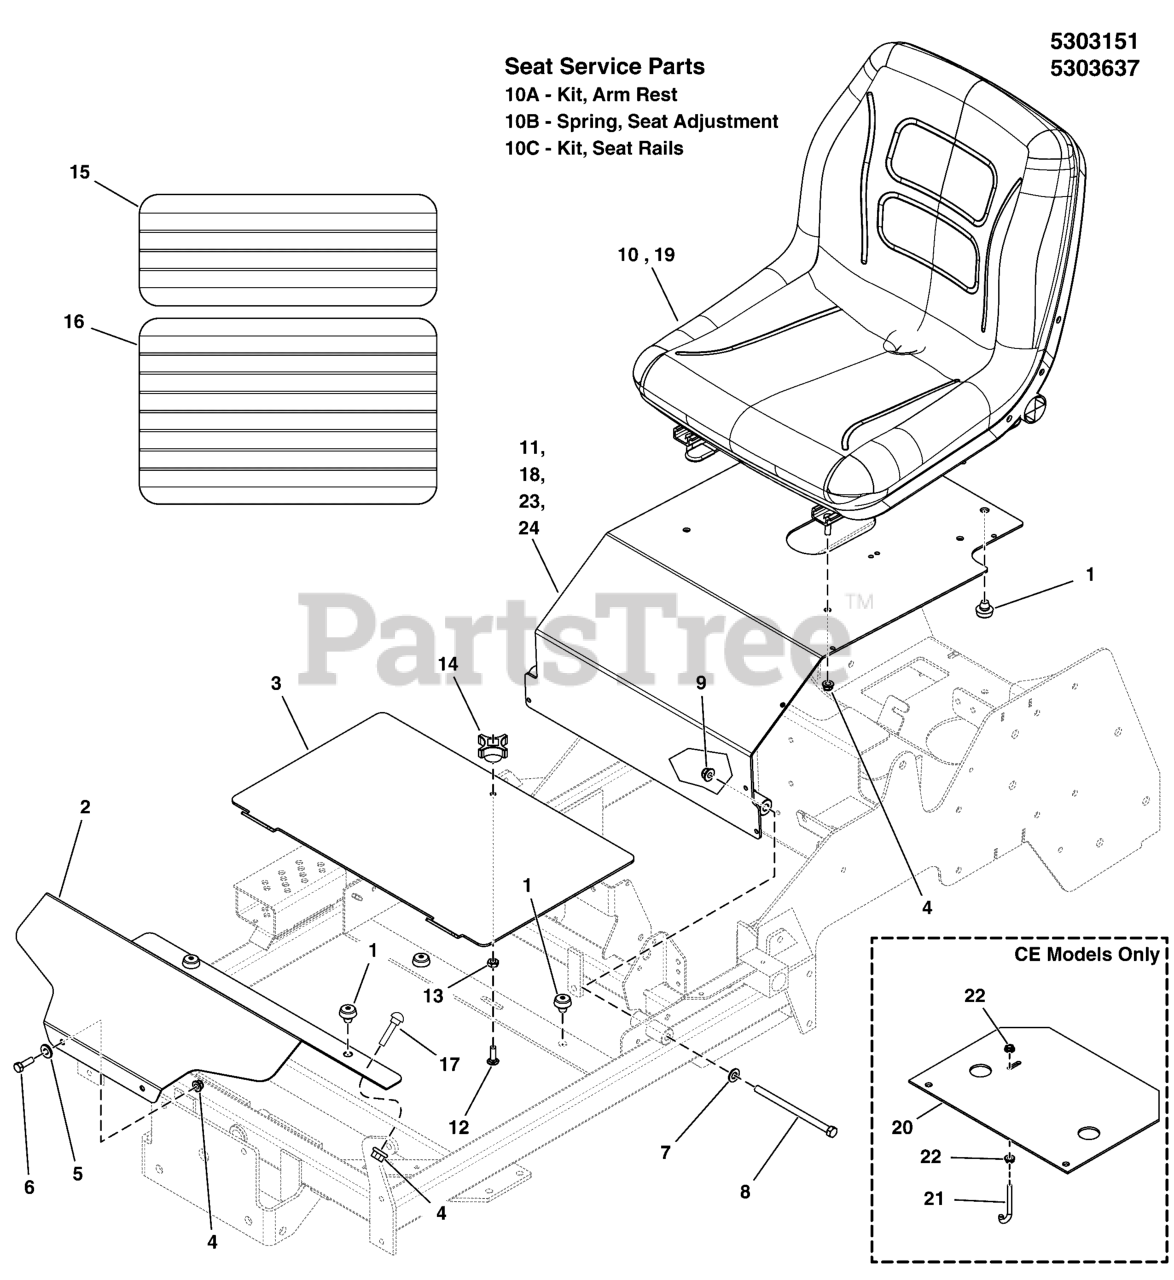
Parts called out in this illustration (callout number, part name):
1	MNT, VBRTN, RBBR
2	PLATE, Floor
3	PLATE, FLOOR PAN, REMOVABLE. IS600 - RED
4	NUT, 5/16-18 HEX NYLOCK FLANGE
5	WASHER, 5/16 F436 FLAT
6	BOLT, 5/16-18 X 1 GD5 YZ
7	WASHER, 3/8 SAE
8	BOLT, 3/8-16 X 6" GD5 CZ
9	NUT, 3/8-16 HEX NYLOCK FLANGE
10	SEAT, NO ARM REST
10A	ARMREST KIT
10B	SPRING, EXTENSION, SEAT ADJUSTMENT (BLK OR SLVR)
10C	SEAT RAIL, KIT, RH AND LH
11	ASSM, SEAT PLATE W/DECALS - IS600Z (5409894B)
12	BOLT, 5/16-18 X 1-1/4, CARRIAGE YZ
13	NUT, 5/16-18,GR8, HEX, CNTR, LK, ZINC/CL
14	KNOB-INT THR .312-18 4-ARM 2.12WD 1.06LG
15	SAFETY WALK, FLOOR REST, 6.00 X 16.00
16	SAFETY WALK, FLOOR PLATE, S50X, 10X16
17	BOLT, 5/16-18 X 1, CARRIAGE
18	ASSM, SEAT PLATE W/DECALS, IS600 ANSI-EXP (5409894B)
19	SEAT, XB-180, NO LOGO, BLACK
20	PLATE, SEAT BELT GUARD - IS600 - RED
21	J-BOLT, 1/4-20 X 1-1/2, CZ
22	NUT, 1/4-20 HEX SERR. FLANGE
23	ASSM, SEAT PLATE W/DECALS, IS600Z-DOM (5415897B)
24	ASSM, SEAT PLATE W/DECALS, IS600Z-EXP (5415897B)
